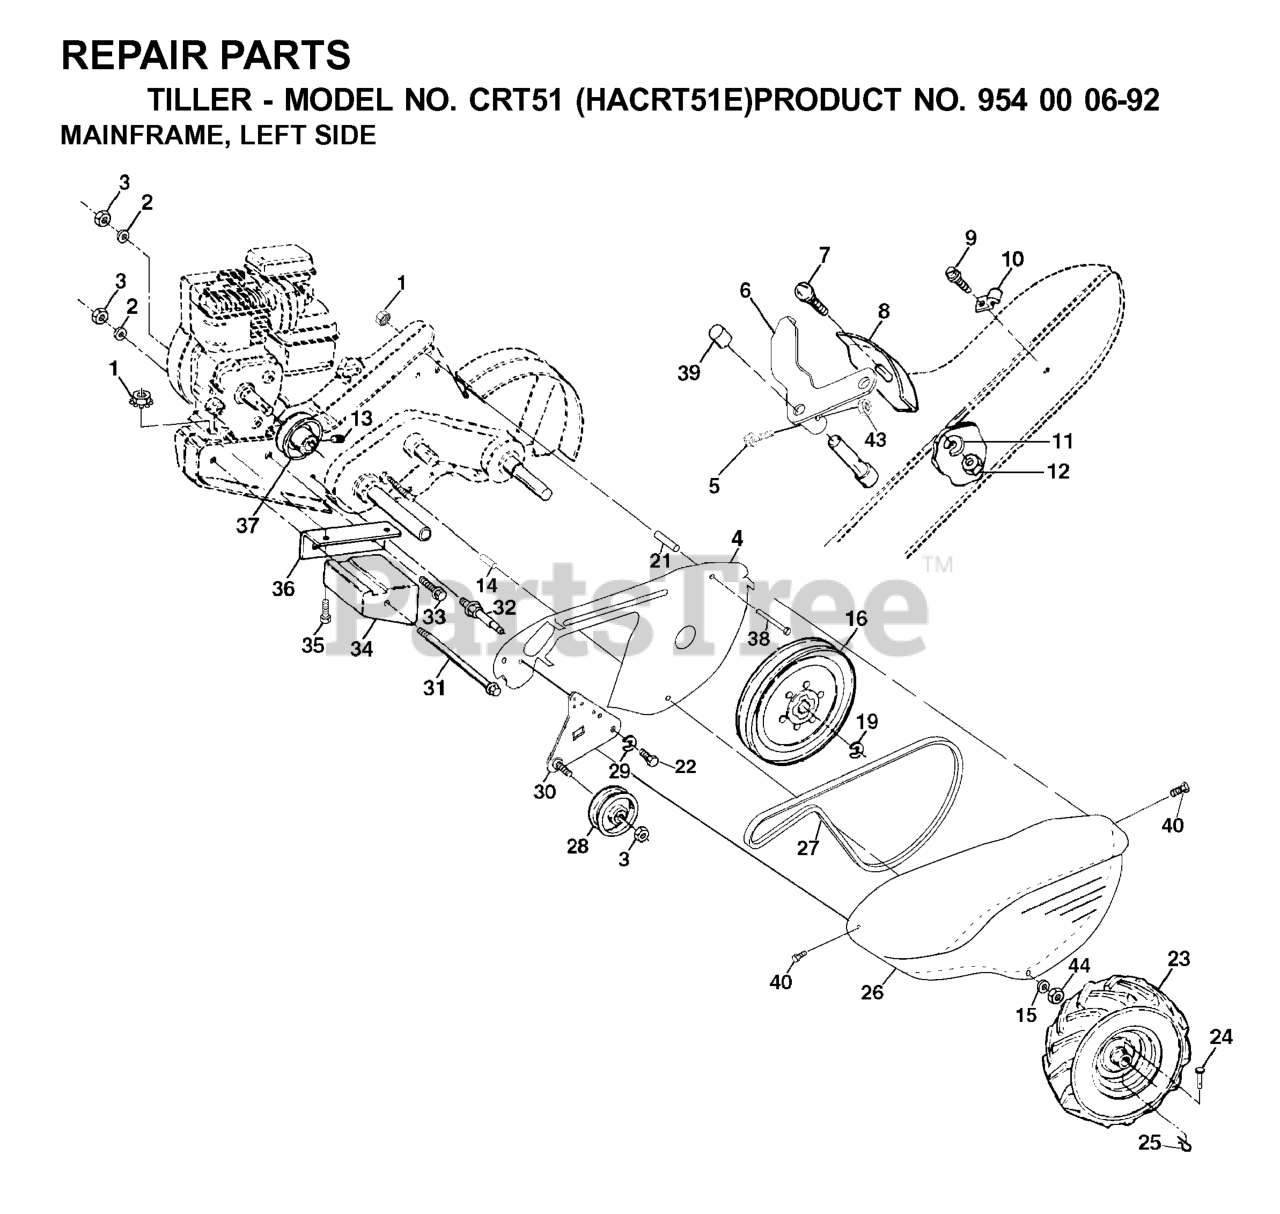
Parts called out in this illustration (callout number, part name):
1	NUT
2	WASHER, LOCK 3/8
3	NUT.HEX.3/8-16UNC
4	SHIELD
5	SCREW, SHIFT LEVER
6	LEVER ASM CRT
8	PANEL.INDICATOR.SHIFT.BLACK
9	TAPPING SCREW
10	CONDUIT.CLIP.PLATED
11	LOCKWASHER
12	NUT
14	SPACER-SPLIT.327 X .42
15	WASHER
16	SHEAVE, TRANSMISSION
19	RETAINING RING LT
21	SPACER CRT
23	TIRE.16X4-8.CHEVRON.TILLER
24	RIVET,DRILLED
25	RETAINER M
26	RP BELT GUARD
27	V-BELT
28	PULLEY-IDLER TI
30	BRACKET.ASM.IDLER.BLACK
31	BOLT.FIN.HEX.3/8-16UNC
32	SHIFT ARM CRT
33	BOLT
34	COUNTERWEIGHT.LH.CRT
35	Bolt Fin Hex 5/16 - 18 Unc x 2 Gr. 2
36	BRACKET LH CRT
37	RP.ENGINE PULLEY
38	BOLT
39	CAP.PLUNGER.BLACK
40	SCREW.HEX.WSH.SLT.#10-24X.50
44	NUT.71038.31-18.HEX.NYLOCK
532124718	VALVE STEM LT
532128952	RIM ASM.2.75 X 8.00.WHITE
